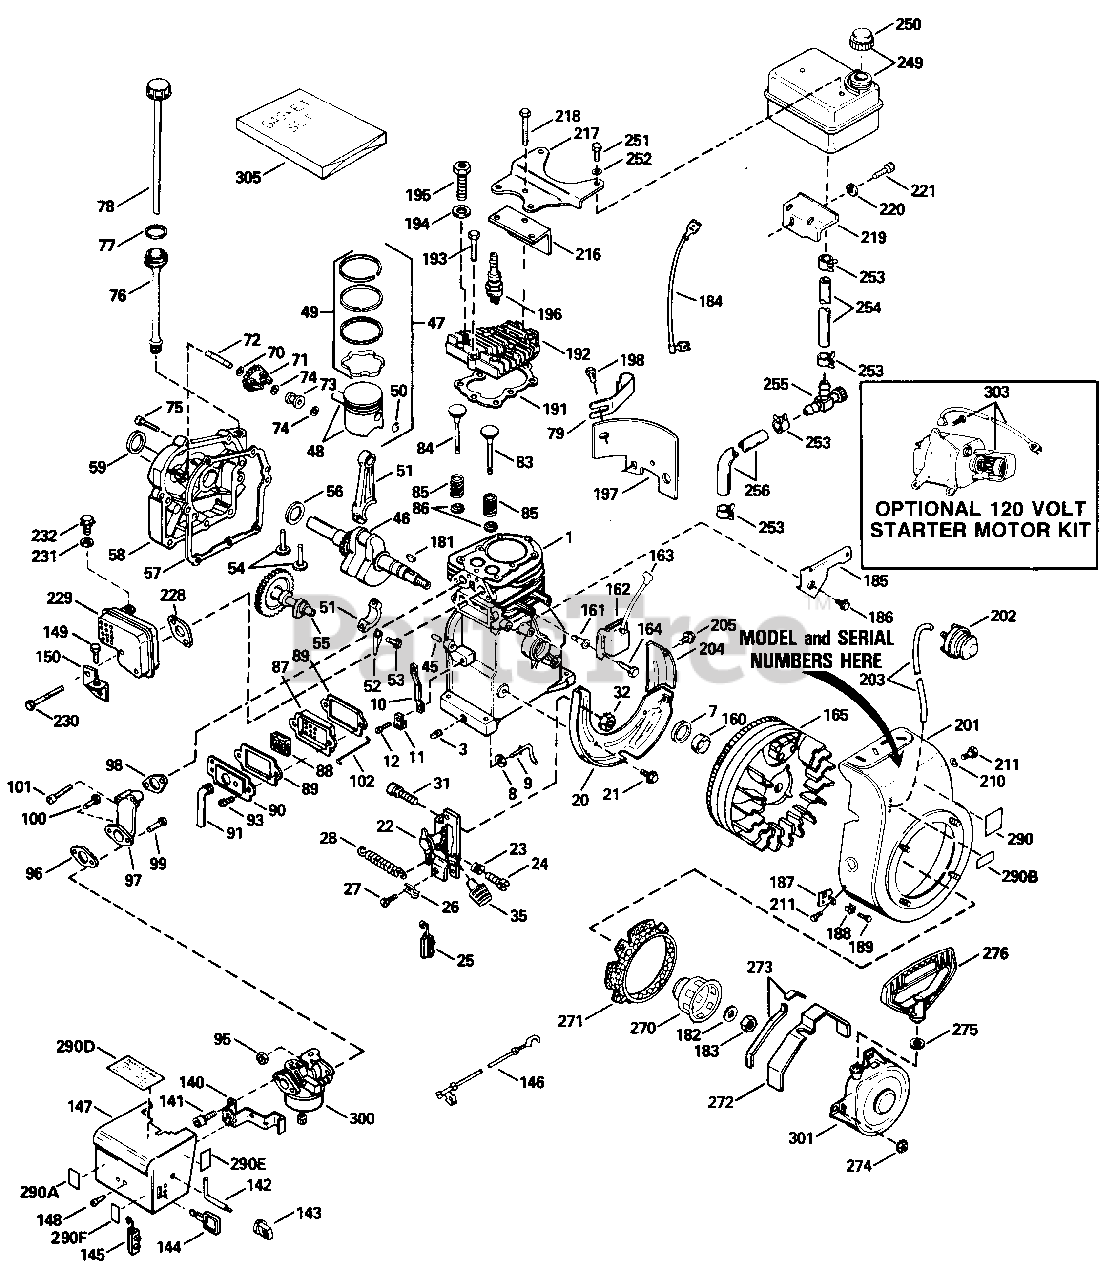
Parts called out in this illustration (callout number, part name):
1	Cylinder Ass'y.
3	Plug, Pipe, 1/4-18
7	Seal, Oil
8	Washer, Flat
9	Rod, Governor
10	Lever, Governor
11	Clamp, Governor Lever
12	Screw, Hex Washer Hd., 8-32 x 5/1 6
20	Baffle, Blower Housing
21	Screw, Hex Washer Hd. Durlok, 1/4-20 x 5/8
22	Control Ass'y., Bracket
23	Spring Compression
24	Screw, Fil. Hd., 5-40 x 7/16
25	Terminal Ass'y.
26	Clip, Conduit
27	Screw, Hex Washer Hd. Sems, 10-32 x 3/8
28	Spring, Extnsion
31	Screw, Fil. Hd. Sems, 8-32 x 1/2
32	Nut, Lock, 8-32
35	Knob, Speed Control
45	Pin, Dowel
46	Crankshaft Ass'y.
47	Piston, Pin & Ring Ass'y. (Std.)
48	Piston & Pin Ass'y. (Std.)
49	Ring Set, Piston (Std.)
50	Ring Piston Pin Retaining
51	Rod Ass'y., Connecting
52	Dipper, Oil
53	Screw, Connecting Rod
54	Lifter, Valve
55	Camshaft (Compression Release)
56	Washer, Thrust
57	Gasket Cylinder Cover
58	Cover, Cylinder
59	Seal, Oil
70	Washer, Flat
71	Gear, Governor
72	Shaft,Mechanical Governor
73	Spool, Governor
74	Ring, Retaining
75	Screw, Hex Hd. Sems, 1/4-20 x 1-1/4
76	Tube Ass'y., Oil Fill
79	Clip, Oil Fill
83	Valve Exhaust (Std.)
84	Valve Intake (Std.)
85	Spring, Valve
86	Cap, Valve Spring
87	Body, Valve Cover
88	Element, Valve Bodyody
89	Gasket Valve Cover
90	Cover, Breather
91	Tube Breather
93	Screw, Fil. Hd. Sems, 10-24 x 1/2
95	Nut & Lock Washer Ass'y., 1/4-28
96	Gasket Carburetor
97	Pipe, Intake
98	Gasket Intake
99	Screw, Hex Hd., 1/4-28 x 7/8
100	Screw, Hex Hd., l/4-28 x 1-11/16
101	Screw, Fil. Hd. Sems, 1/4-20 x1-19/32
102	Link, Governor to Throttle
140	Bracket, Choke
141	Screw, Fil. Hd. Sems, 10-32 x 1/2
142	Rod, Choke
143	Knob, Choke Control
144	Key, Ignition
145	Terminal Ass'y.
146	Wire, Ground
147	Cover, Carburetor
148	Screw, Pan Hd. Sems, 8-32 x 5/16
149	Screw, Hex Hd. Sems, Taptite, 10-24 x 3/8
150	Bracket, Carburetor Cover
160	Spacer, Flywheel Key
161	Stud, Solid State Mounting
162	Solid State Ass'y.
163	Cover, Spark Plug
164	Screw, Hex Hd. Sems, 10-24 x 1
165	Flywheel (w/Ring Gear)
181	Key Flywheel
182	Washer, Belleville
183	Nut Flywheel
184	Wire, Ground
185	Bracket, Hld Down
186	Screw, Hex Washer Hd. Self-Tap Sems, 1/4-15 x 7/8
187	Bracket, Grommet Mounting
188	Grommet, Plastic
189	Screw, Pan Hd. Taptite, 8-32 x 3/8
191	Gasket Cylinder Head
192	Head, Cylinder
193	Screw, Hex Flange Hd., 5/16-18 x 1 1/2
194	Washer, Flat
195	Screw, Special Hex Hd., 5/16-18X 1 1/2
196	Plug, Spark
197	Extension, Blower Housing
198	Screw, Fil. Hd. Sems, 10-24 x 1/2
201	Housing, Blower
202	Primer Ass'y.
203	Line Primer
204	Extension, Baffle
205	Screw, Hex Washer Hd. Shake-proof Self-Drilling, 8-18 x 7/16
210	Washer, Flat
211	Screw, Hex Hd. Sems, 1/4-28 x 7/16
216	Baffle, Heat
217	Plate, Fuel Tank
218	Screw, Hex Flange Hd., 5/16-18 x 2
219	Bracket, Fuel Tank Mounting
220	Washer, Flat
221	Screw, Hex Hd., w/Belleville Washer, 1/4-20 x 11/16
228	Gasket, Exhaust
230	Screw, Fil. Hd. Sems, 1/4-20 x 2 1/2
231	Washer, Flat
232	Screw, Hex Washer Hd. Sems, 1/4-20 x 1/2
249	Tank Ass'y., Fuel
250	Cap, Fuel Tank
251	Screw, Hex Washer Hd. Self-Tap Sems, 1/4-15 x 7/8
252	Washer, Flat
253	Clamp, Fuel Line
254	Line, Fuel
255	Valve, Shut-Off
256	Line, Fuel
270	Cup, Starter
271	Screen, Starter Cup
272	Guard, Starter
273	Seal, Snow Guard
274	Nut & Lock Washer, 1/4-28
275	Washer, Flat
276	Handle, Starter
290	Decal, Name
290A	Decal, Instruction
290B	Decal, Primer
290D	Decal, Warning
290E	Decal, Instruction
290F	Decal, Instruction
300	Carburetor
301	Starter Rewind
303	Electric Starter Kit
305	Gasket Set
